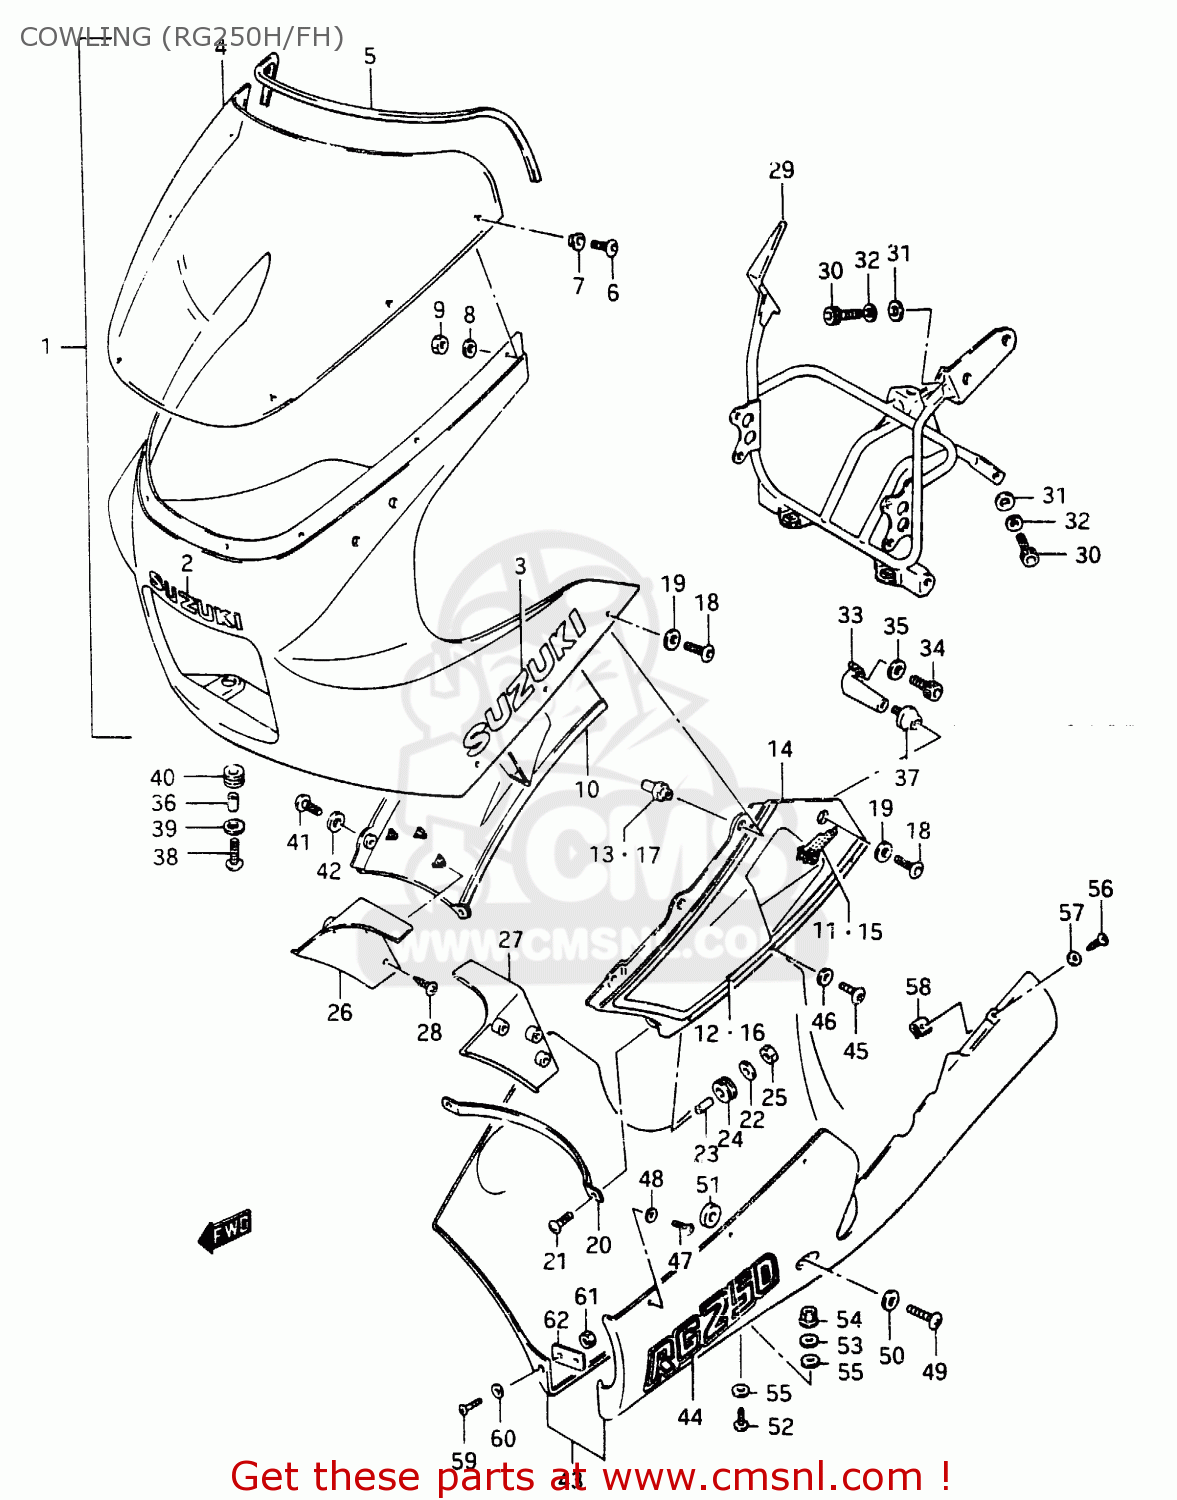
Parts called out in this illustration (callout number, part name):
1	COWLING ASSY (BLUE)
2	EMBLEM
3	EMBLEM
4	WINDOW
5	MOLDING
6	SCREW(5X14)
7	CUSHION
8	WASHER,5MM
9	NUT 8MM
10	COVER, COWLING RH
11	EMBLEM
12	TAPE SET, RH
13	NUT,COWLING COVER
14	COVER, COWLING LH
15	EMBLEM
16	TAPE SET, LH
17	NUT,COWLING COVER
18	SCREW(6X20)
19	WASHER(6.5X16X1.2)
20	PANEL, COWLING LOWER
21	SCREW
22	WASHER (6.5X20X1.2)
23	SPACER (6.8X10X10)
24	CUSHION
25	NUT 6MM
26	GUIDE PLATE, RH
27	GUIDE PLATE, LH
28	SCREW
29	BRACE, COWLING
30	BOLT
31	WASHER
32	WASHER,LOCK,8.
33	SPACER, COWLING LOWER
34	BOLT
35	WASHER
36	SPACER(6.5X11.5X12)
37	CUSHION,COWLING
38	SCREW(6X20)
39	WASHER
40	CUSHION
41	SCREW(6X30)
42	WASHER(6.5X16X1.2)
43	COWLING ASSY, UNDER
44	EMBLEM
45	SCREW(6X12)
46	WASHER(6.5X16X1.2)
47	SCREW
48	WASHER
49	SCREW
50	WASHER(6.5X16X1.2)
51	CUSHION
52	SCREW
53	WASHER
54	NUT
55	WASHER
56	SCREW
57	WASHER
58	NUT
59	SCREW
60	WASHER
61	NUT 4MM
62	BRACKET
